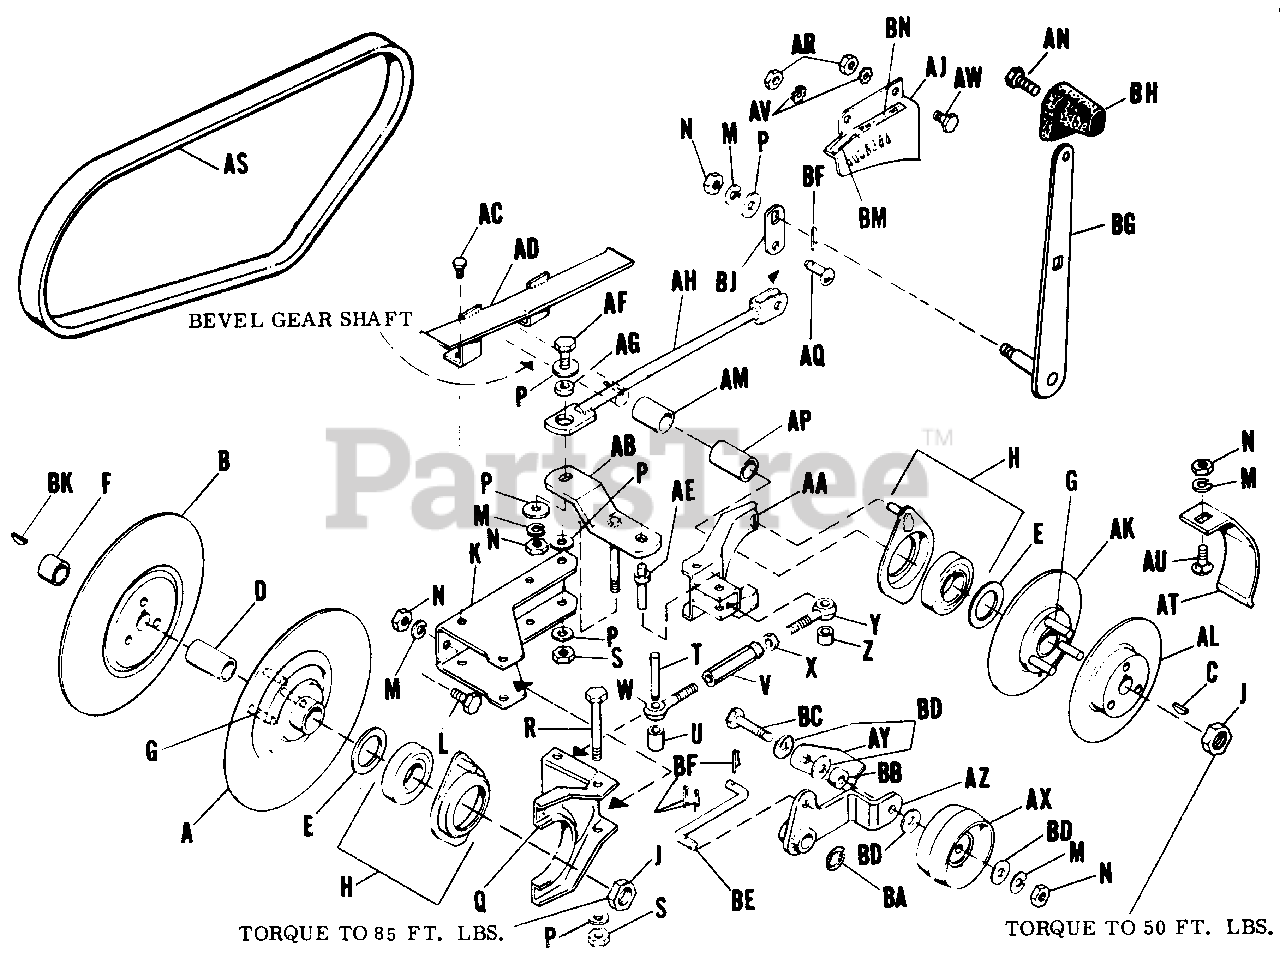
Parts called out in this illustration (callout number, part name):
A	Pulley-Half Assembly
B	Pulley-Half & Bushing Assy.
D	Driven Slide Spacer
H	Retainer Ring/Bearing Assy.
J	Hex Jam Nut, Lock, 3/4"-16
K	Variable Speed Bracket
L	Hex Capscrew, 3/8"-16 x 7/8"
M	Lock Washer, 3/8"
N	Hex Nut, 3/8"-16
P	Plain Washer, 3/8"
Q	Transmission Fork Assy.
R	Special Screw
S	Hex Nut, 3/8"-16 Lock
T	Pivot Pin
V	Turnbuckle Body
W	Eyebolt, R.H.
X	Hex Nut, 3/8"-24
Y	Eyebolt, L.H.
AA	Bevel Gear Housing Fork Assy.
AB	Fork, Rocker Assy.
AC	Screw, Taptite, 1/4"-20 x 5/8"
AD	Belt Guard Assy.
AF	Hex Capscrew, 3/8"-16 x 1-1/4"
AH	Arm Assy.
AK	Pulley-Half Assy.
AL	Pulley-Half Assy.
AM	Slide Spacer
AN	Thread Forming Screw, 1/4"-20 x 7/8"
AP	Slide Spacer (Teflon Coated)
AR	Nut, Twin Pilot
AS	BELT, HI, 54"
AT	Belt Guard
AU	Carriage Bolt, 3/8"-16 x 3/4"
AV	Lock Washer Ext. Tooth, 5/16"
AW	Special Screw, 5/16"-18 x 3/8"
AX	Idler Pulley
AY	Idler Belt Stop
AZ	Idler Lever Assy.
BA	Retaining Ring
BC	Hex Capscrew, 3/8"-16 x 2"
BD	Plain Washer, 5/16"
BE	Clutch Link
BF	Cotter Pin
BG	Lever Assy.
BK	Key, Woodruff
